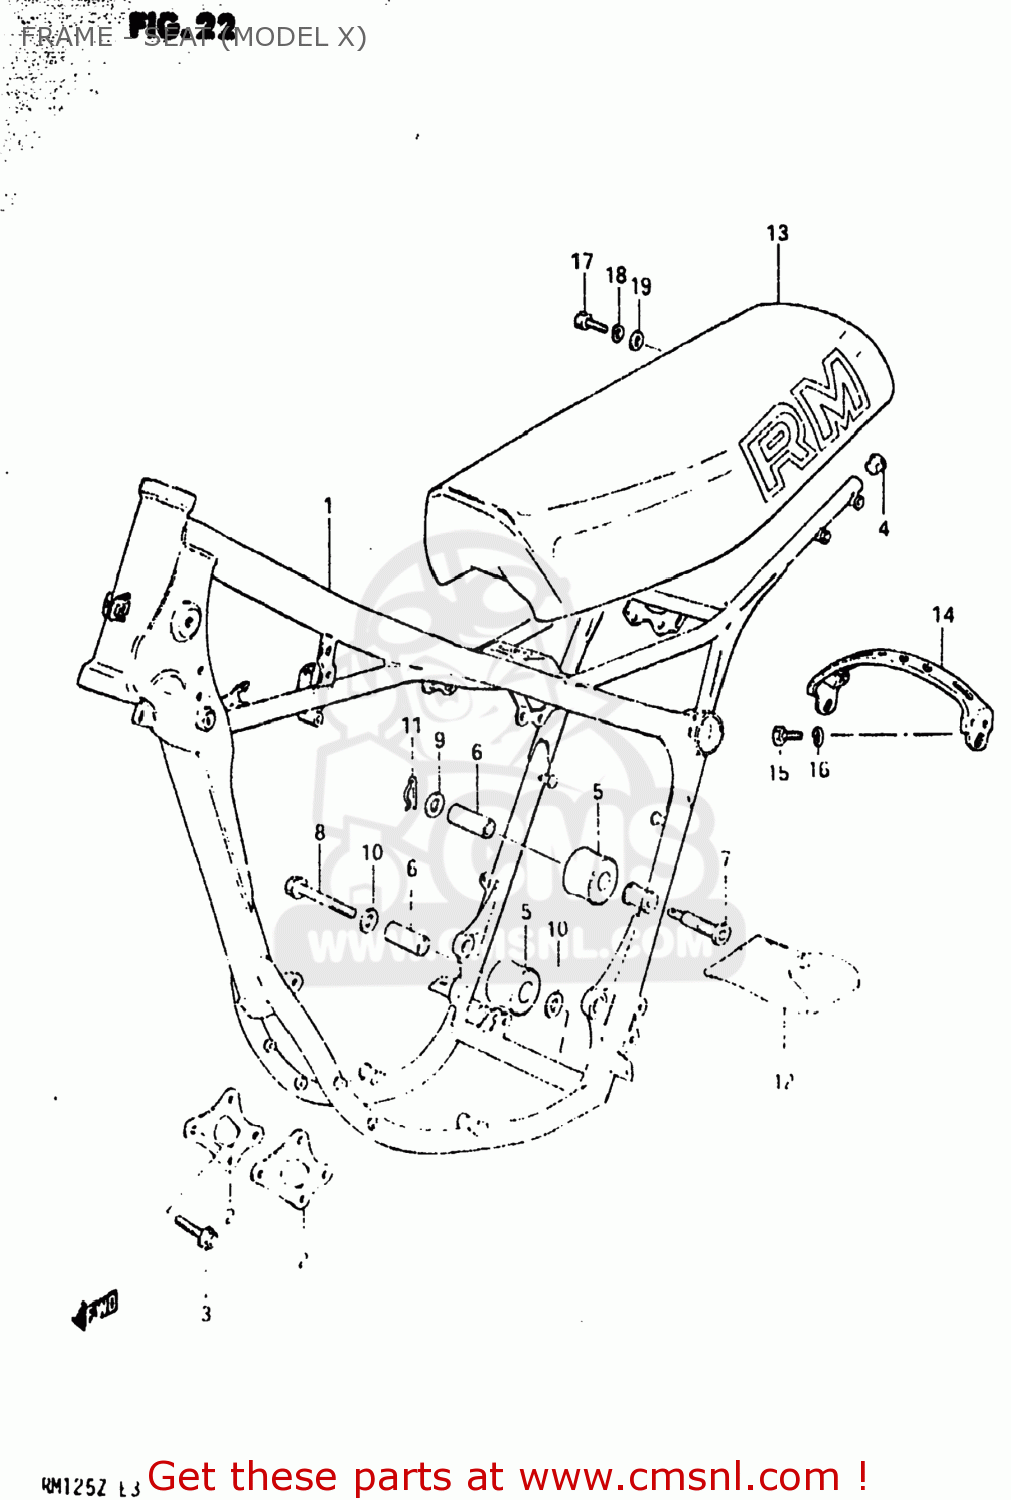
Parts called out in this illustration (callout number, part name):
1	FRAME
2	PLATE,ENGINE MOUNTING
3	BOLT(8X25)
4	PLUG(OD:17)
5	ROLLER,CHAIN LENGTH CONTROL
6	SPACER,CHAIN LENGTH ROLLER
7	BOLT,CHAIN LENGTH ROLLER
8	BOLT(8X45)
9	WASHER
10	WASHER
11	CLIP
12	TOOL SET
13	SEAT ASSEMBLY
14	PLATE SEAT REAR STAY
15	BOLT, UPPER
16	LOCK WASHER
17	BOLT
18	WASHER,LOCK,8.
19	WASHER (8.5X20X2.6)
